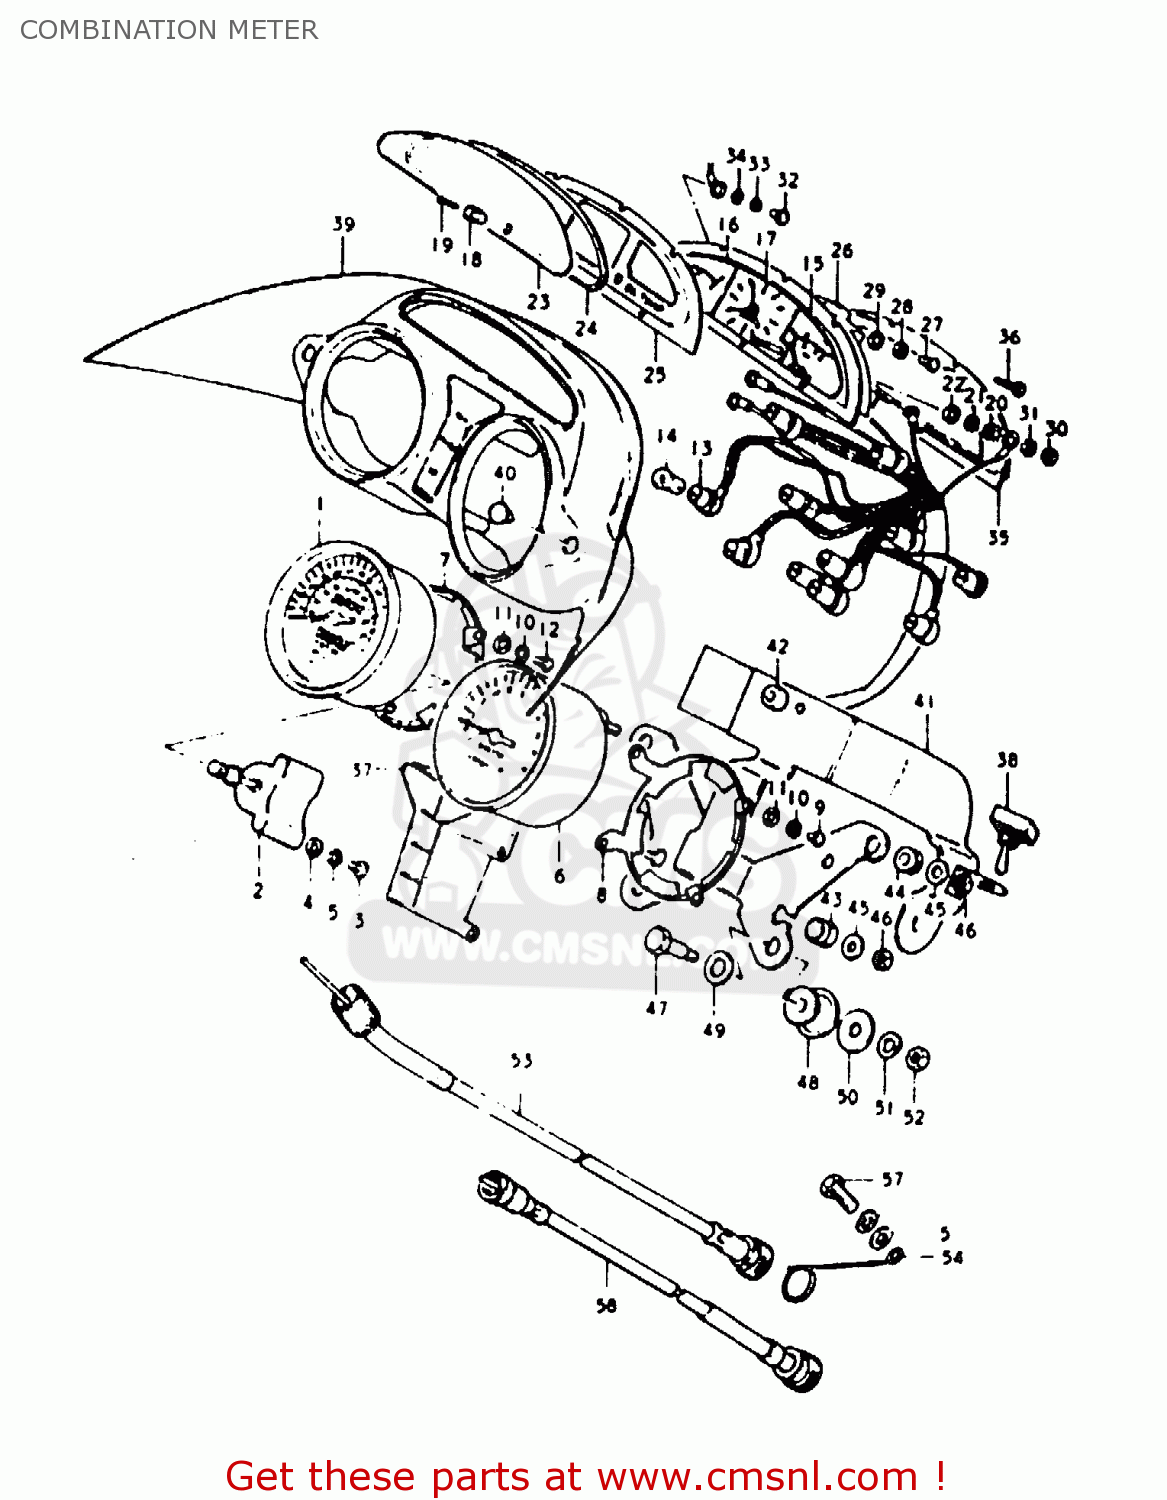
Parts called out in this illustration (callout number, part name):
1	SPEEDOMETER (KM/H)
2	HOLDER,TRIP METER RESET
3	SCREW
4	WASHER
5	LOCK WASHER
6	TACHOMETER
7	HOLDER,METER
8	HOLDER,TACHOMETER
9	SCREW
10	LOCK WASHER
11	WASHER
12	SCREW
13	SOCKET,METER
14	BULB(12V3.4W,STANLEY,A72A)
15	METER,OIL TEMPERATURE
16	FUEL METER
17	CLOCK ASSEMBLY
18	KNOB
19	SCREW,CLOCK KNOB
20	NUT
21	LOCK WASHER
22	WASHER
23	GLASS,COMBINED FUEL METER
24	GASKET,COMBINED FUEL METER
25	PLATE,COMBINED FUEL METER
26	CASE,LOWER
27	SCREW
28	LOCK WASHER
29	WASHER
30	NUT
31	LOCK WASHER
32	SCREW
33	LOCK WASHER
34	WASHER
35	BRACKET,FUEL METER
36	SCREW,METER
37	CASE,PILOT BULB
38	SWITCH,CLOCK
39	HOOD,METER
40	CAP,ACCESSORY HOLE
41	BRACKET,COMBINATION METER
42	CUSHION,FUEL METER
43	CUSHION
44	CUSHION,METER
45	WASHER,SPEEDOMETER
46	NUT
47	BOLT(8X31)
48	CUSHION,METER
49	WASHER
50	WASHER (8.5X29X1.6)
51	LOCK WASHER
52	NUT
53	CABLE ASSEMBLY,SPEEDOMETER
54	GUIDE,SPEEDOMETER CABLE
55	WASHER 6MM
56	LOCK WASHER
57	BOLT, UPPER
58	CABLE ASSEMBLY,TACHOMETER
